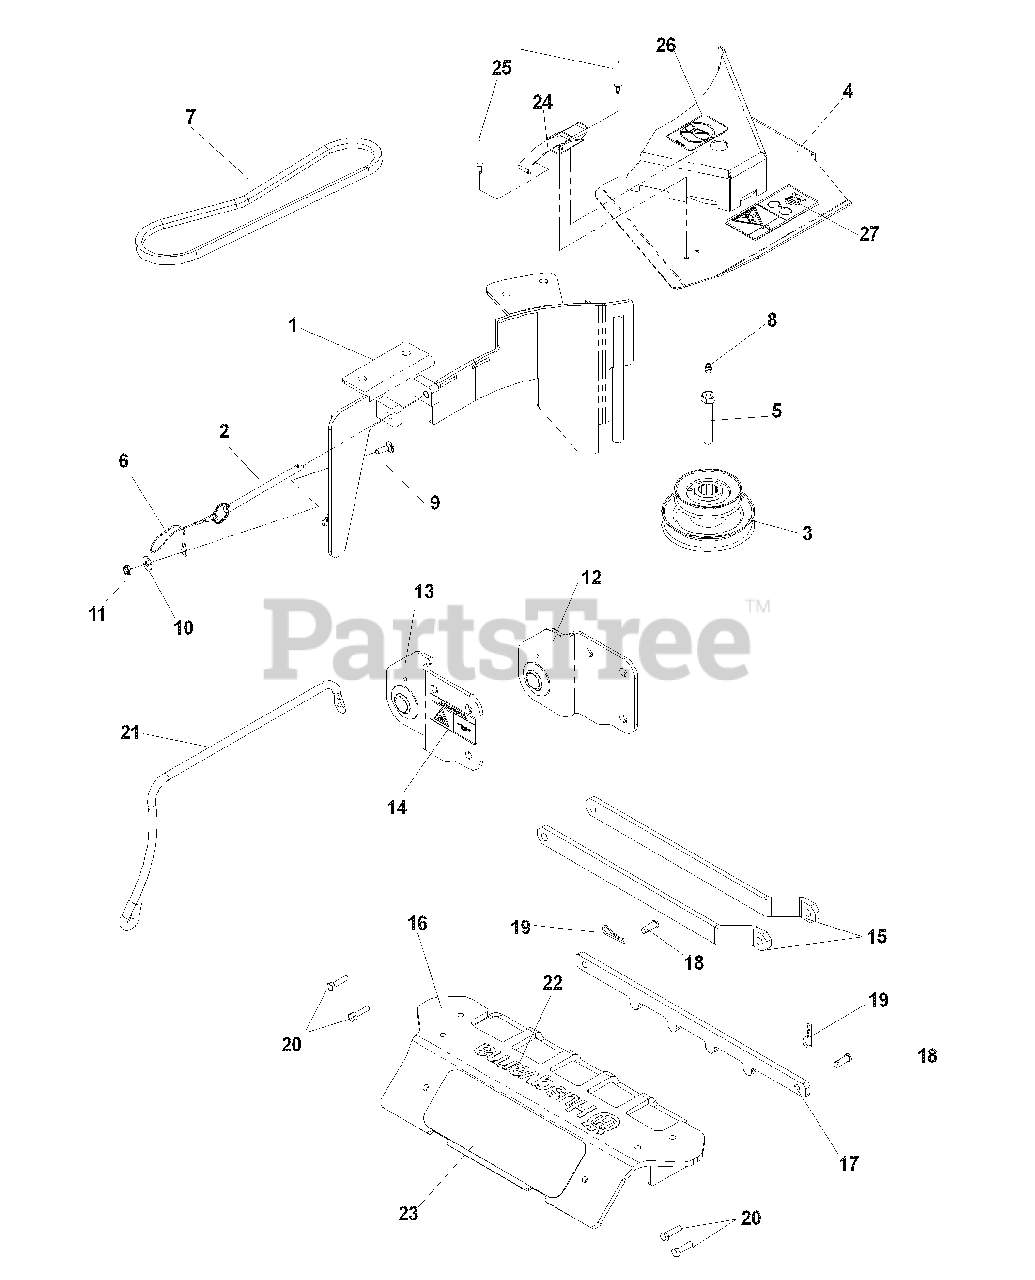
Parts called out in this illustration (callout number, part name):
1	BLOWER DECK PLATE, 48"
3	STACK PULLEY, 48"
4	BELT SHIELD, 48"
5	HCS, 7/16-20 x 2 1/2, GR8
8	ZERK
9	RHSNB, 1/4-20x3/4, GR2
10	WASHER, 1/4
11	NUT, 1/4-20, JAM, NYLOC
12	HITCH BRACKET, LEFT
13	HITCH BRACKET, RIGHT
14	DECAL, HOT SURFACE
16	WEIGHT BAR
17	HOLD DOWN, WEIGHT BAR
18	CLEVIS PIN
19	SPRING RETAINER
20	HCS./5/16-18x1 1/4
21	HOSE SUPPORT
22	DECAL, HUSQVARNA
23	ABRASIVE PAD
24	DRAW LATCH
25	RIVET, BLIND, 5/32 DIA
26	DECAL, NO STEP
27	DECAL, DANGER BLT DRIVES
